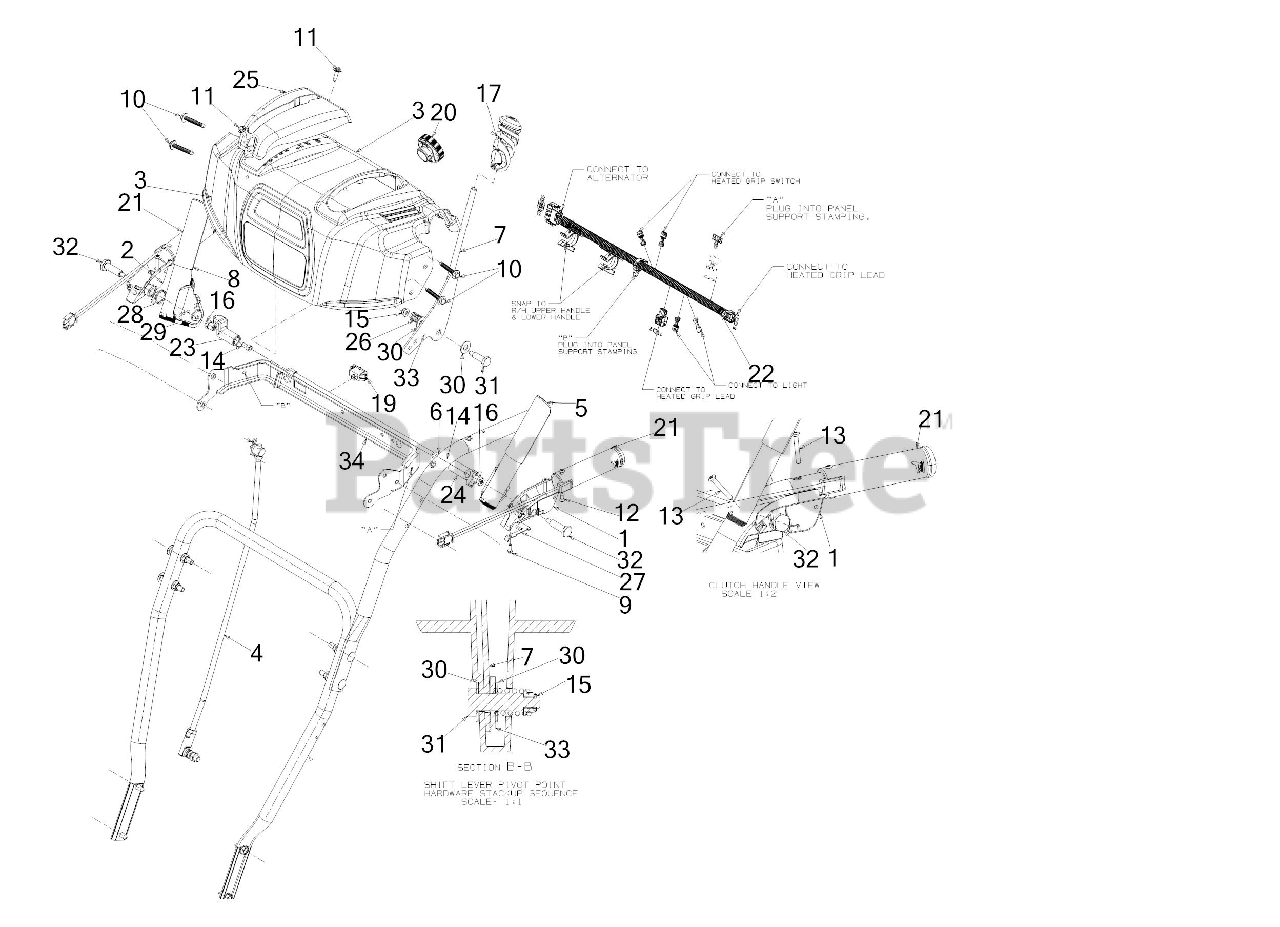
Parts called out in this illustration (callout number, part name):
1	CLUTCH LOCK HANDLE ASSEMBLY (LH)
2	CLUTCH LOCK HANDLE ASSEMBLY (RH)
3	HANDLE PANEL ASSEMBLY
4	SHIFT ROD ASSEMBLY
5	HANDLE ASSEMBLY (LH)
8	ENGAGEMENT HANDLE ASSEMBLY (RH) (BLACK)
9	SCREW #8-16 x .50
10	SCREW 1/4-20 x 1.625
11	SCREW 1/4-10 x .750
12	SCREW #10-16 x .625
13	SCREW #10-24 x 1.375
14	SCREW 1/4-20 x .50
15	FLANGE LOCK NUT
16	HEX NUT W/PATCH
17	PTO HANDLE GRIP .355 ID
19	HEATED GRIP SWITCH
20	HEADLIGHT ASSEMBLY
22	HEATED GRIPS HARNESS
24	CLUTCH LOCK CAM
25	HANDLE PANEL COVER
26	COMPRESSION SPRING
27	CLUTCH SPRING
28	TORSION SPRING
29	RUBBER BUMPER
30	FLAT WASHER
31	SHOULDER SCREW
32	SHOULDER SCREW .437 x 1.345 1/4-20
33	FRICTION WASHER
34	HANDLE SUPPORT BRACKET
